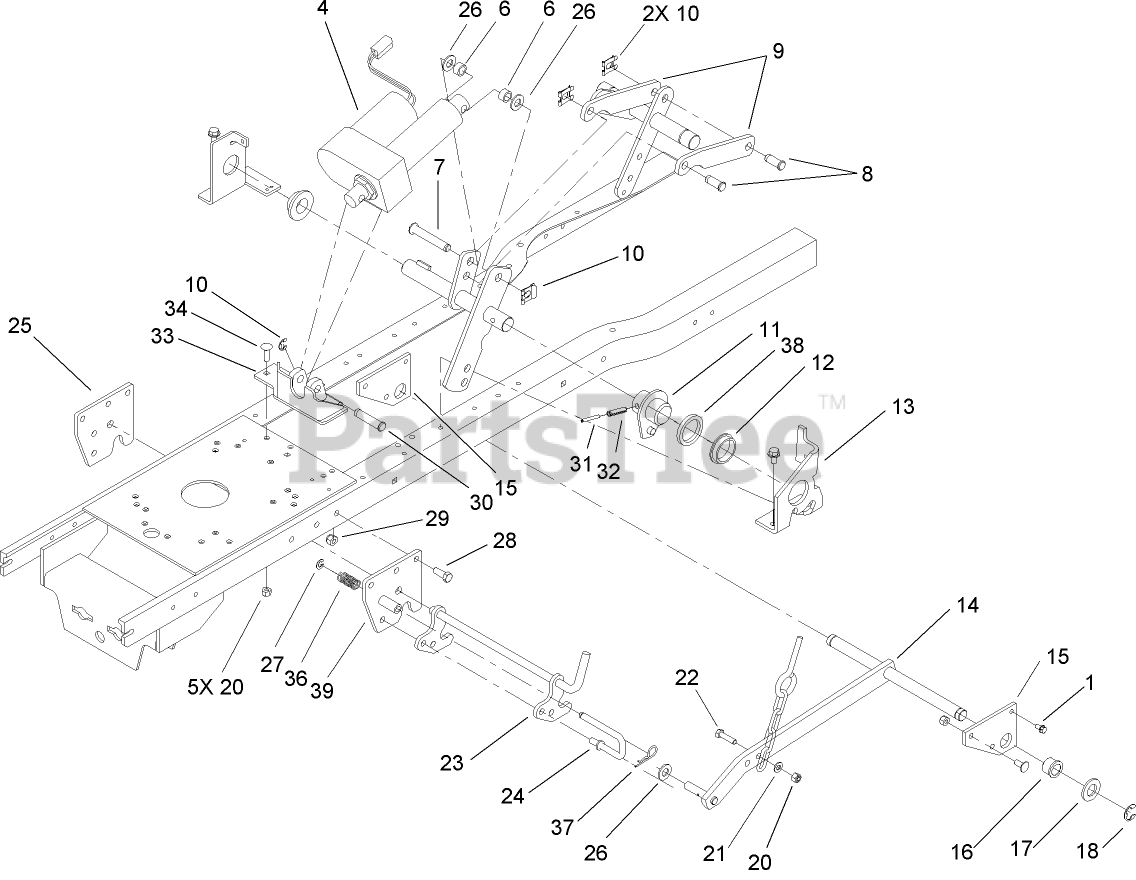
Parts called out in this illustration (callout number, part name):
1	SCREW-HWHTF
4	ACTUATOR
6	SPACER
7	PIN-CLEVIS
8	PIN-CLEVIS
9	STRAP-LINK, LIFT
10	CLIP-PIN
11	END CAP ASM
12	BUSHING
13	BRACKET-ARM, LIFT
14	LIFT BAR ASM
15	PLATE-LIFT, REAR
16	BUSHING-FLANGE
17	WASHER-FLAT
18	E-RING
20	NUT-LOCK, NI
21	WASHER-PLAIN
22	SCREW-HH
23	MIDHITCH LATCH ASM
24	ROD-CATCH
25	PLATE-HITCH
26	WASHER-FLAT
27	RING-RETAINING
28	SCREW-HH
29	NUT-LOCK, NI
30	PIN-CLEVIS
31	PIN-SPRING
32	PIN-ROLL
33	ACTUATOR BRACKET ASM
34	SCREW-CARR
36	SPRING-COMPRESSION
37	PIN-HAIR
38	SPACER
39	MIDHITCH ASM
